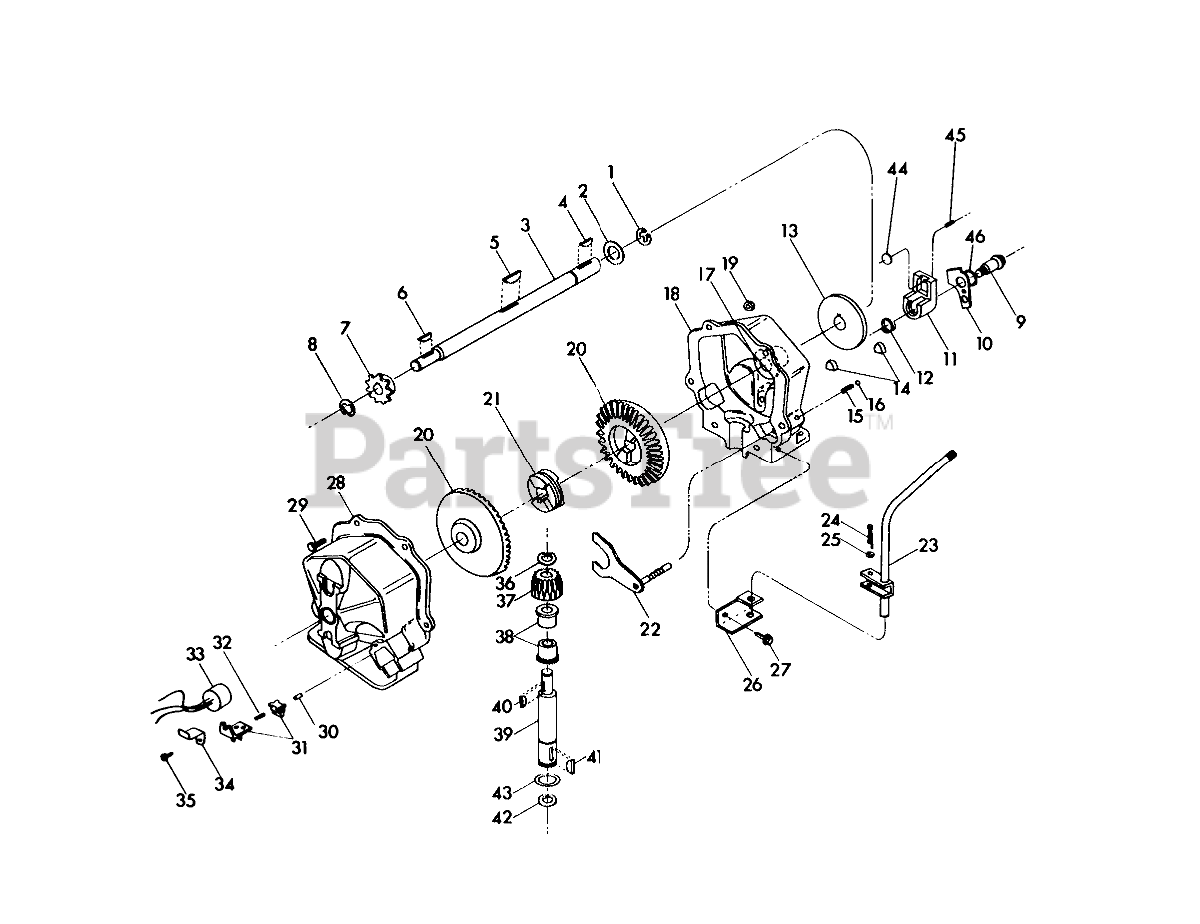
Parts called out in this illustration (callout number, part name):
1	RETAINING RING
2	Washer, Plain
3	Output Shaft
4	Woodruff Key
5	Hi Pro Key
6	Key, Woodruff
7	Sprocket
8	RETAINING RING
9	Shoulder Bolt
10	Actuating Lever
11	Jaw, Brake
12	Compression Spring
13	BRAKE DISC
14	FRICTION PUCK
15	Spring, Detent
16	Ball Detent
17	Bearing Flange
18	Housing
19	Locknut
20	Bevel Gear
21	CLUTCH COLLAR
22	Shaft, Detent
23	Shift Lever
24	Cotter Pin
25	Plain Washer
26	Shift Lever Bracket
27	Hex Head Bolt
28	Housing
29	Bolt Hex Head
30	Pin, Actuating
31	Board Terminal & Carrier Contact Set
32	Spring, Compression
33	Module, Control
34	Retainer, Module, Control
35	Self Tapping Screw
36	Ring, Retaining
37	Pinion, Bevel
38	Bearing, Flange
39	Shaft, Input
40	Key, Woodruff
41	Key, Woodruff
42	Retaining Ring
43	Washer, Plain
44	Spacer
45	Set Screw
46	Washer Kit
